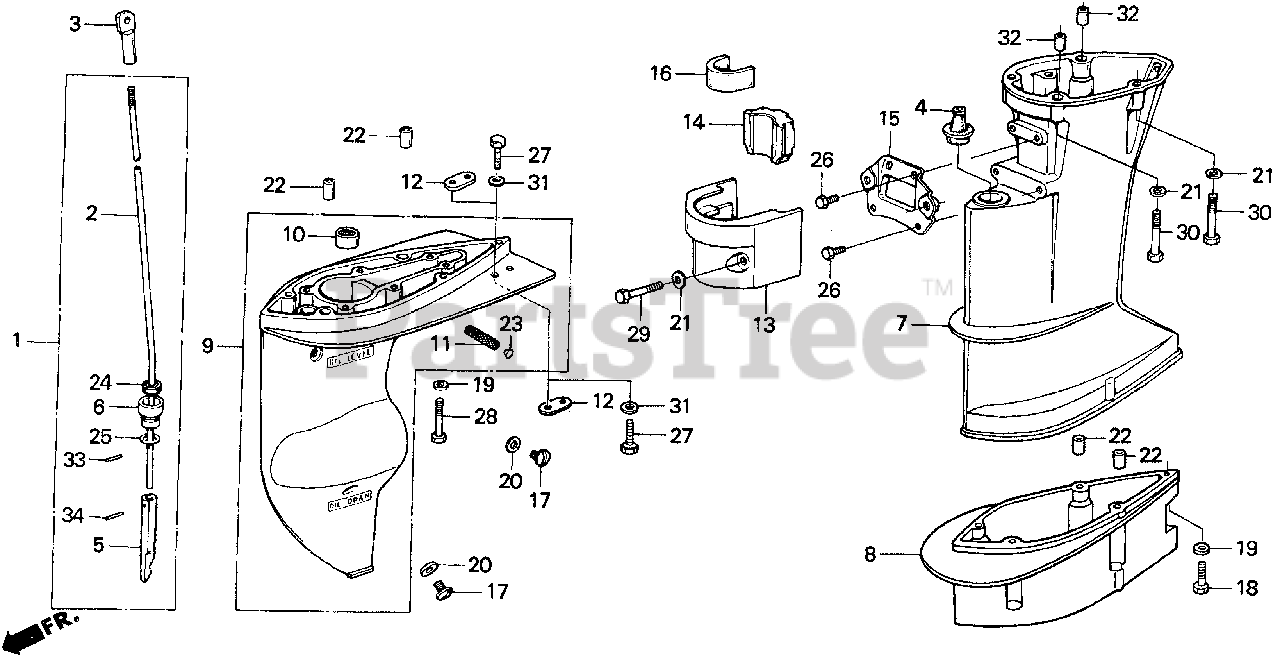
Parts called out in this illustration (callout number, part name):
1	ROD, GEARSHIFT (L)
2	ROD, GEARSHIFT (L)
3	JOINT, SHIFT ROD
4	GROMMET, ROD
6	HOLDER, SEAL
7	CASE, EXTENSION *B107* (L) (SENIOR BLUE) (NOT AVAILABLE)
9	CASE, GEAR *B107* (SENIOR BLUE)
10	BEARING, NEEDLE (15X21X16)
11	SCREEN, WATER
12	METAL, ANODE
13	HOUSING, SETTING (LOWER) *B107* (SENIOR BLUE) (NOT AVAILABLE)
14	RUBBER A, MOUNTING (LOWER)
15	PLATE, SETTING (LOWER)
16	RUBBER B, SETTING (LOWER)
17	BOLT, OIL CHECK
19	WASHER, PLAIN (6MM)
20	WASHER, NYLON (8MM)
21	BOLT, FLANGE (6X35)
21	WASHER, PLAIN (8MM)
22	PIN, DOWEL (8X10)
22	BOLT, STRAIGHT SLOT (4X6)
23	WASHER, PLAIN (6MM)
23	PLUG, SEALING (10MM)
24	PIN, SPLIT
24	PIN, SPLIT (2.0)
24	SEAL, WATER (6MM)
25	O-RING (13.8X2.5)
25	CLIP, WIRE
26	BOLT, HEX. (6X12)
26	BOLT, HEX. (6X8)
27	BOLT, HEX. (6X16)
28	BOLT, HEX. (6X40)
29	BOLT, HEX. (8X40)
30	BOLT, HEX. (8X50)
31	WASHER, PLAIN (6MM)
32	PIN A, DOWEL (10X14)
33	PIN, SPRING (2.5X12)
34	ROLLER (2.5X11.8)
